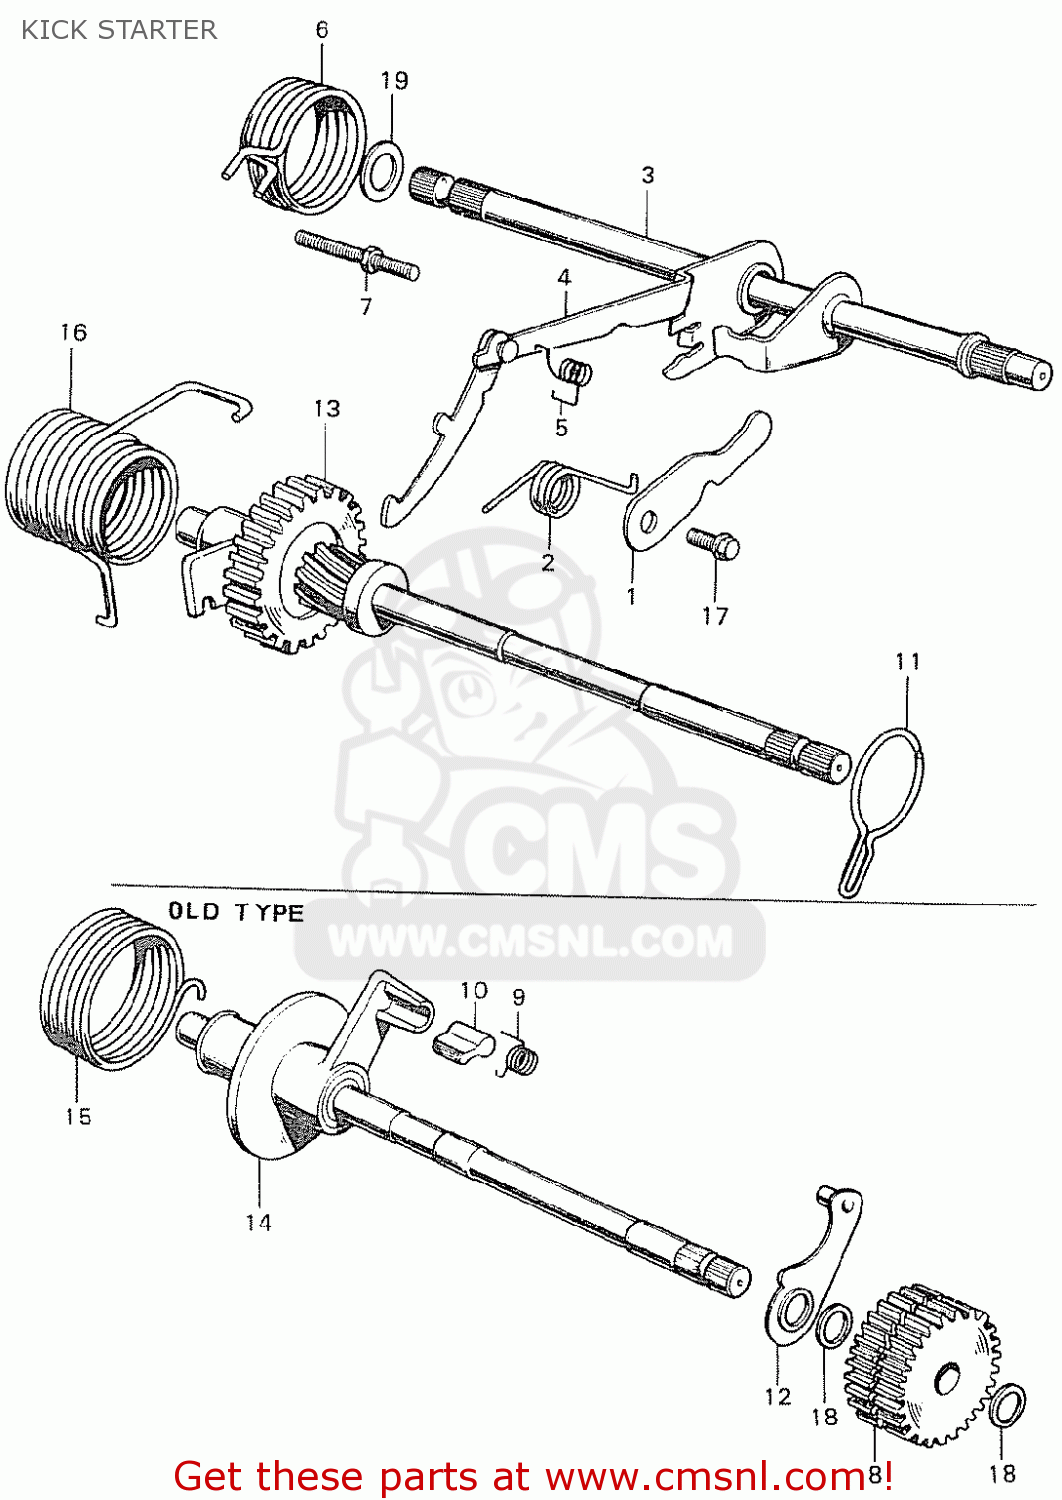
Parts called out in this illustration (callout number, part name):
1	STOPPER,DRUM
2	SPRING STOPPER
3	SPINDLE, SHIFT
4	ARM GEAR SHIFT
5	SPRING SHIFT
6	SPRING SHIFT
7	PIN, SHIFT RETURN
8	PINION STARTER
9	SPRING,KICK
10	PAWL STARTER
11	SPRING,KICKSTART
12	GUIDE STARTER
13	SPINDLE KICK
14	SPINDLE STARTER
15	SPRING, STARTER
16	SPRING KICK
17	PIVOT SHIFT
18	WASHER, THRUST, 1
19	WASHER, 12.2M/M
